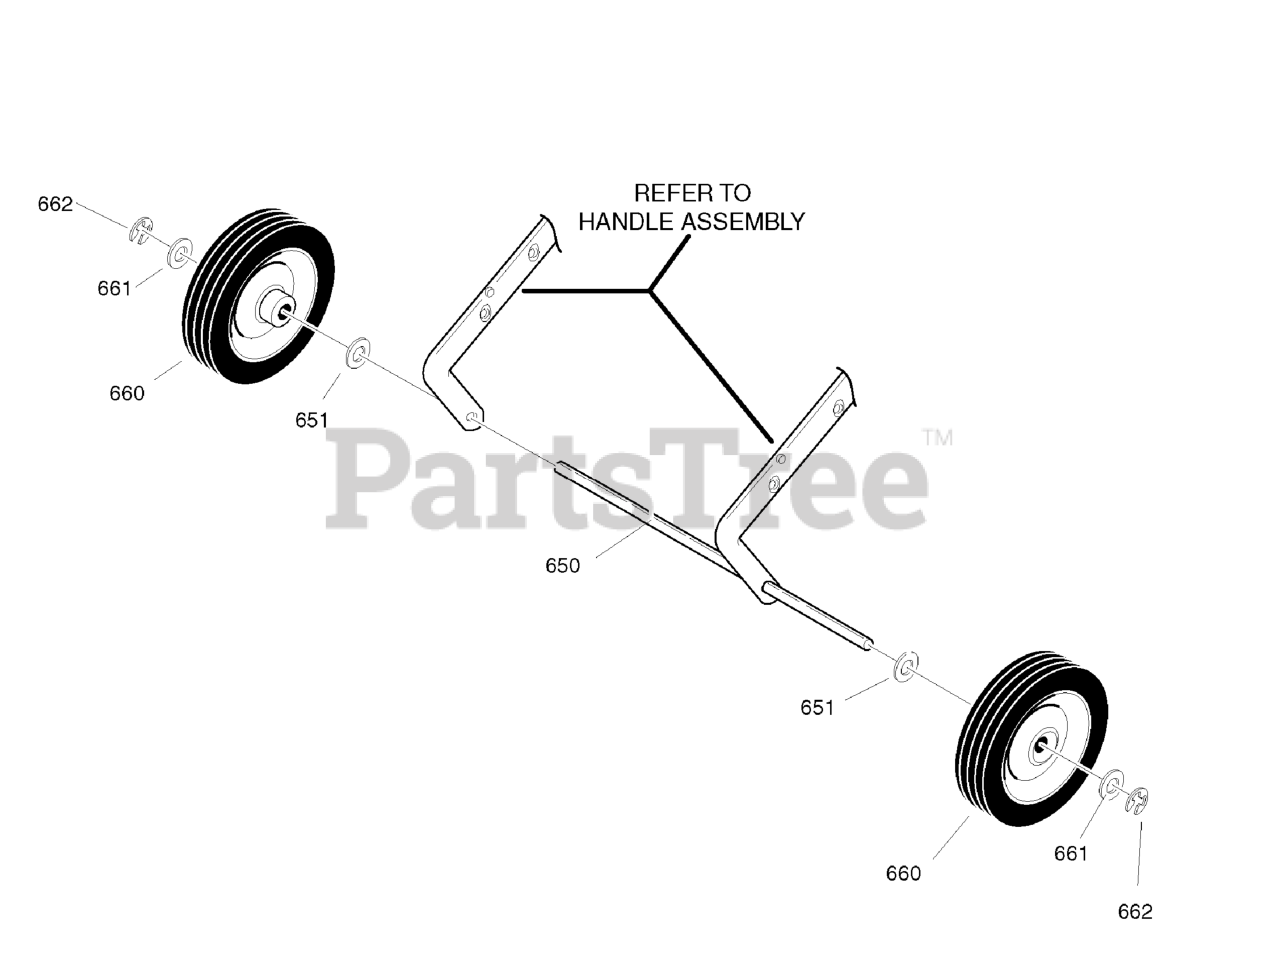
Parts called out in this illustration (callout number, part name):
650	AXLE, 20.53 WHL 20/21
651	WASHER, FLAT .391 X 1.00 X .125
660	TIRE & RIM
661	WASHER, FLAT .391 X 1.00 X .125
662	RING, RETAINER
